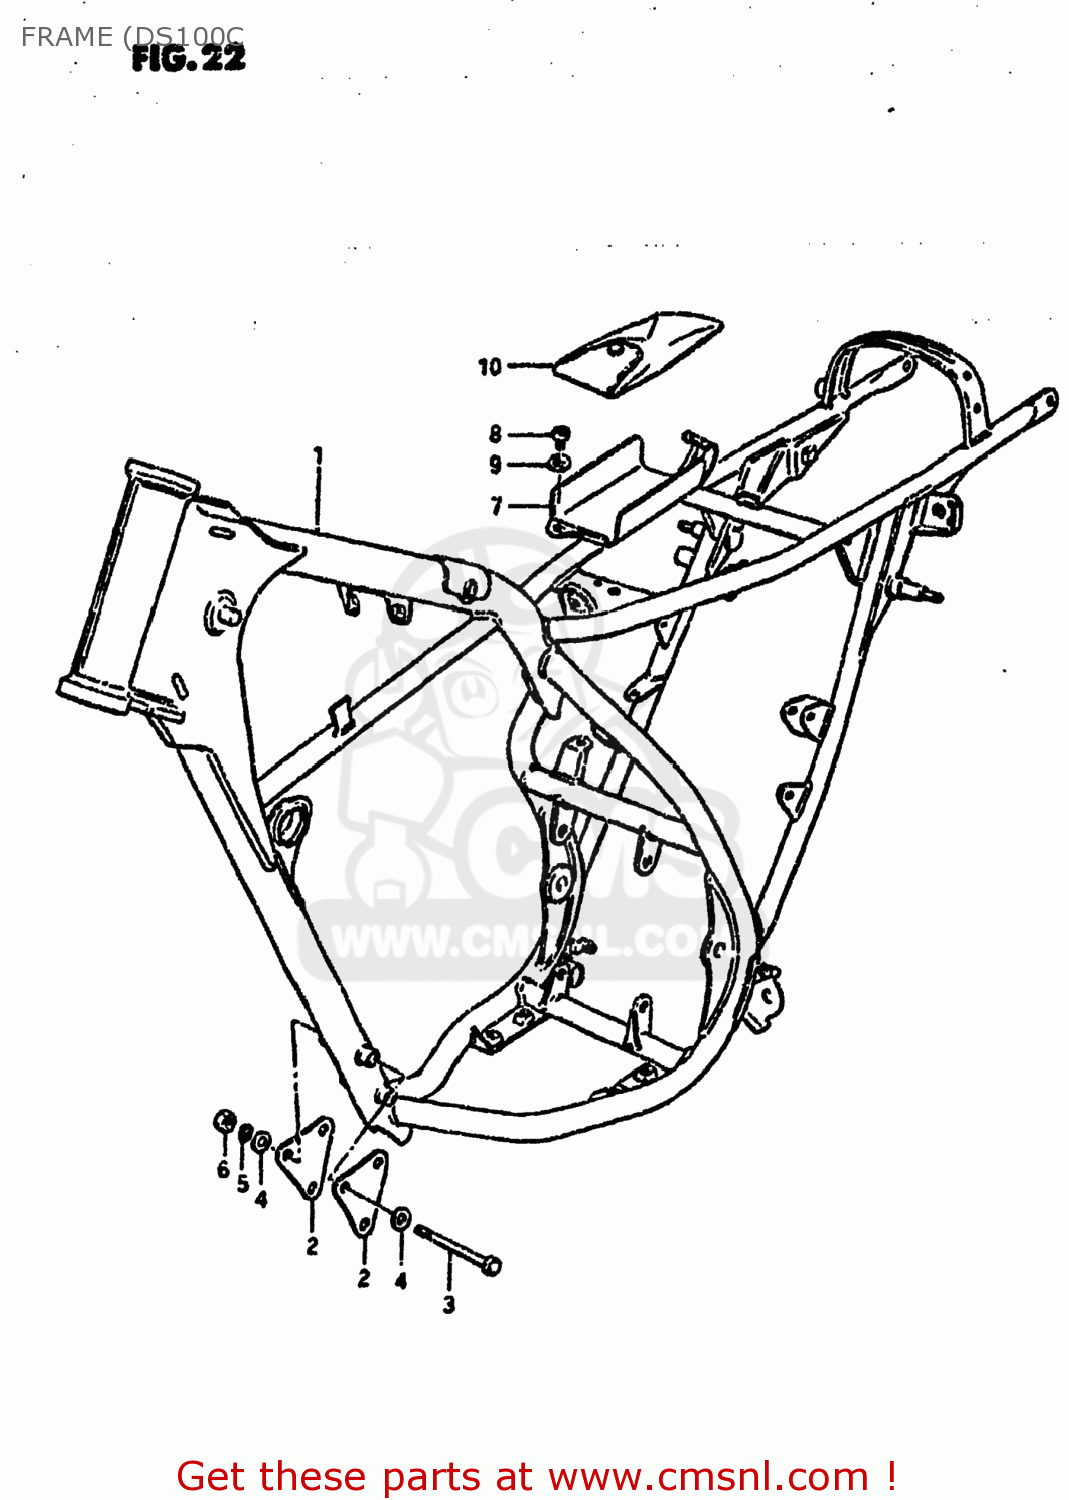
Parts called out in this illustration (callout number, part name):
1	FRAME
2	PLATE,ENG MTG
3	BOLT,8X75
4	WASHER
5	LOCK WASHER
6	NUT
7	HOLDER,TOOL
8	SCREW
9	WASHER
10	TOOL SET
